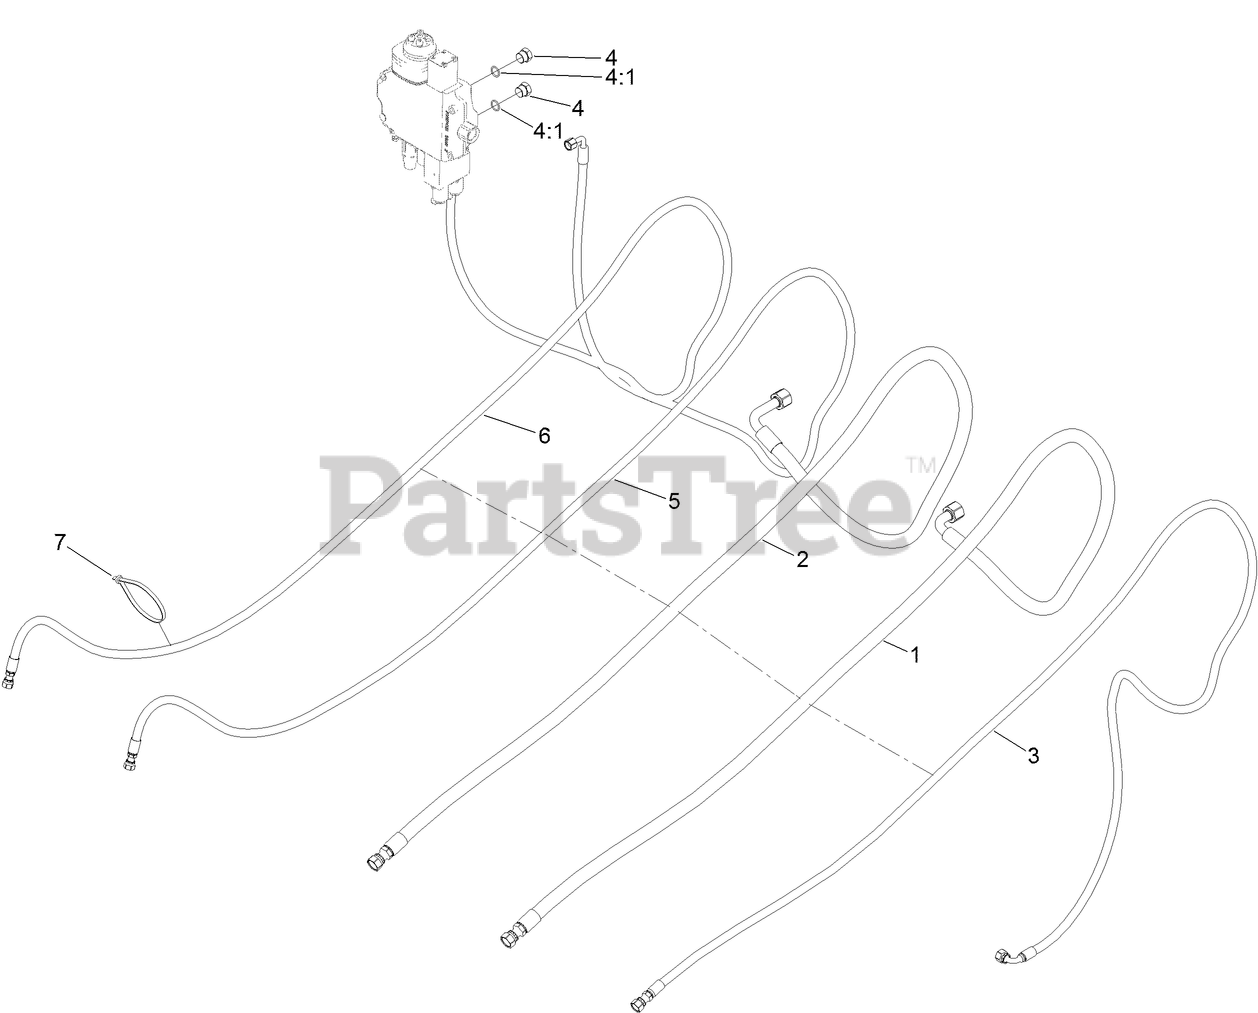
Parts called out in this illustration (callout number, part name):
1	HOSE-HYD
2	HOSE-HYD
3	HOSE-HYD
4	PLUG-HH
4:1	O-RING
5	HOSE-HYD
6	HOSE-HYD
7	TIE-CABLE
